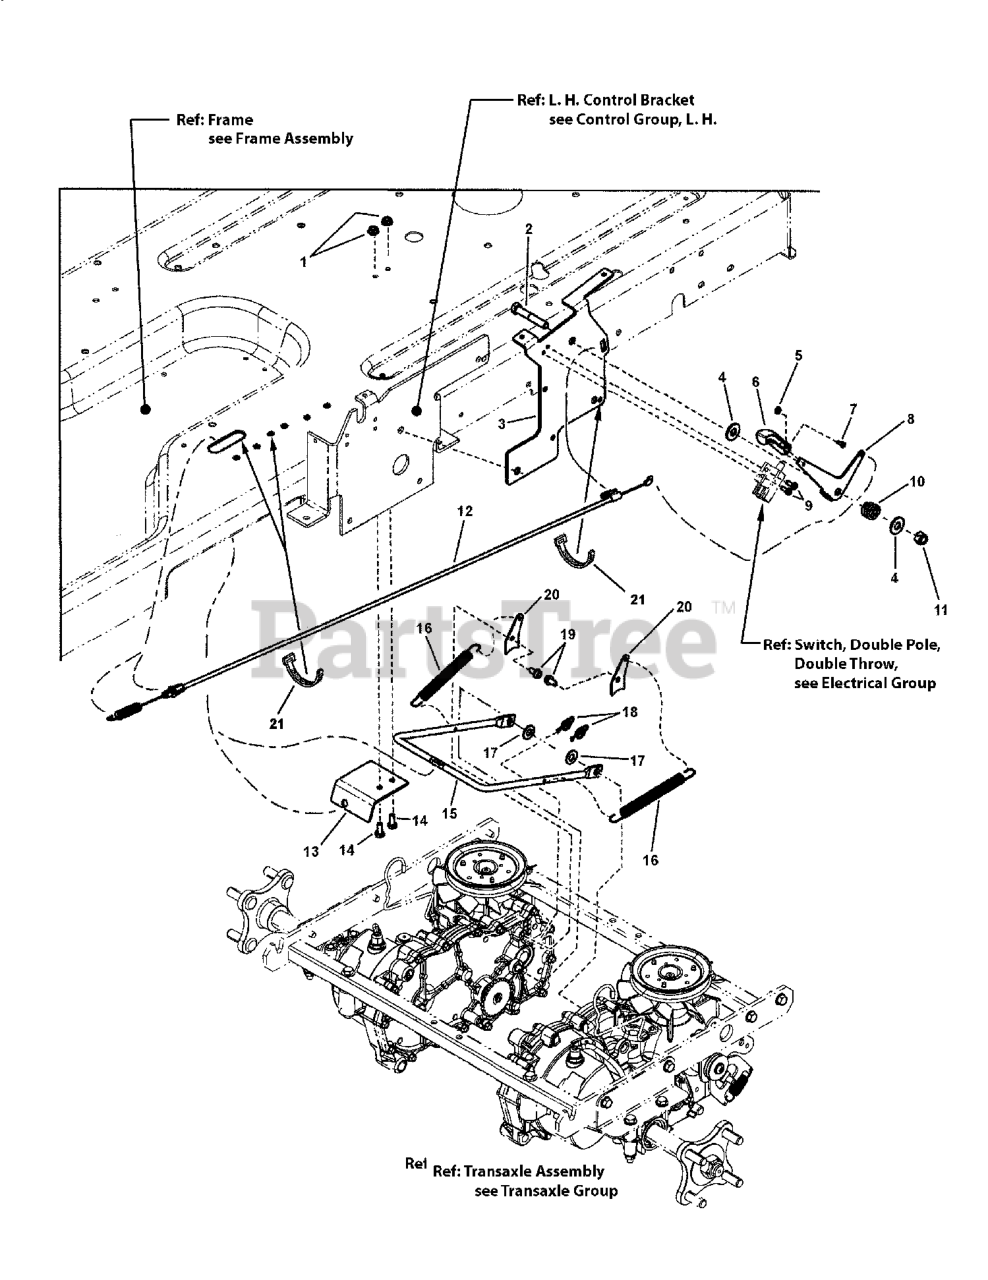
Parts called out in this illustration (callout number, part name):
1	NUT, Hex Flange Lock, 1/4-20
2	CAPSCREW, Hex Head, 3/8-16 x 2-1/4, GR 5
3	BRACKET, Lever, Park Brake
4	WASHER, Flat, 7/16
5	NUT, Hex, #8-32 GR 2B
6	LEVER, Throttle Control
7	SCREW, Cross Recess Filister Head, #8-32 x 3/8, GR 2
8	LEVER, Park Brake
9	SCREW, Hex Washer Head, Self-Tap, #10-24 x 1/2 (Torx)
10	SPRING, Friction Pack
11	NUT, Hex Nyloc, 3/8-16
12	CABLE, Park Brake, RZT
13	BRACKET, Cable, Park Brake
14	CAPSCREW, Hex Head, 1/4-20 x 5/8, GR 5
15	ROD, Park Brake, RZT
16	SPRING, Extension, 4-1/4"
17	WASHER, Flat, 3/8 (SAE)
18	COTTER PIN, 1/2
19	SCREW, Hex Washer Head, Self-Tap, 1/4-20 x 1/2
20	TAB, Spring, Park Brake
21	CABLE TIE, 7.0
